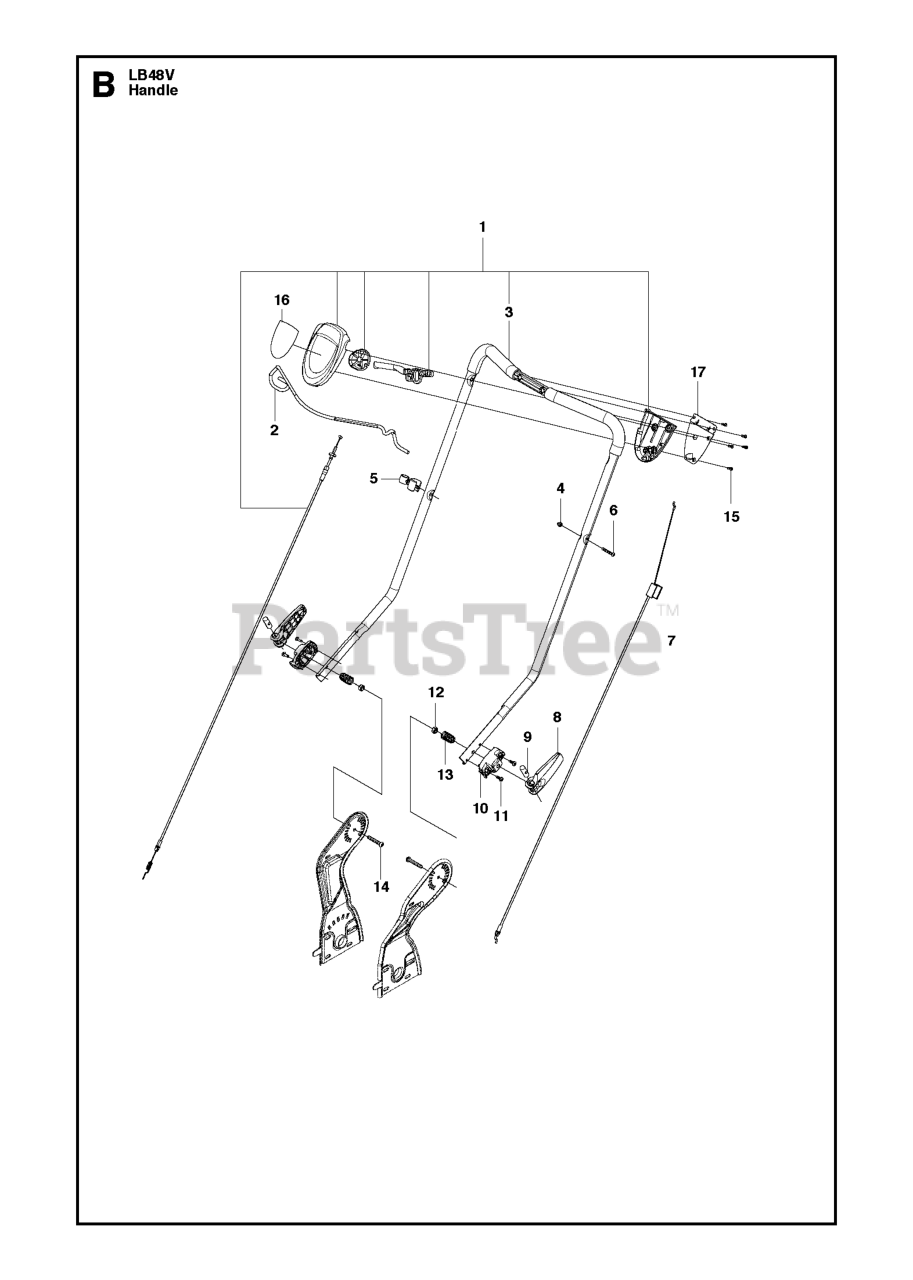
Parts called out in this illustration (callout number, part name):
1	DECAL.READ.OWN.MAN.SYMBOL.LT
2	DECAL.CHASSIS.HOT.MUFFLER
3	DECAL.FNDR.SDLE.BRAKE.CLUTCH.6
4	DECAL.80.DBA.AUSTRALIA
5	DECAL.WARN.FUEL.RESERVE
7	DECAL.ENGINE.WARNING
8	DECAL.PARKING.BRAKE.SADDLE.LT
9	DECAL BTRY SYMBOLS
10	DECAL.PEDALS.SYMBOL
11	DECAL.TICKMARK.6MIL.AUSTRALIA
12	DECAL.PEDAL.HUSQ.CROWN
13	DECAL.DECK.6MIL.EURO.NOSTEP
14	DECAL.SDPNL.GT2.SET.GTH3052TDF
15	DECAL.DECK.6MIL./DEF.SHLD.WARN
16	DECAL.BADGE.170MM.TEXTLOGO.
17	BRACKET, DRIVE CONTROL
18	DECAL.MOWER.SCH.48/54.PREM
